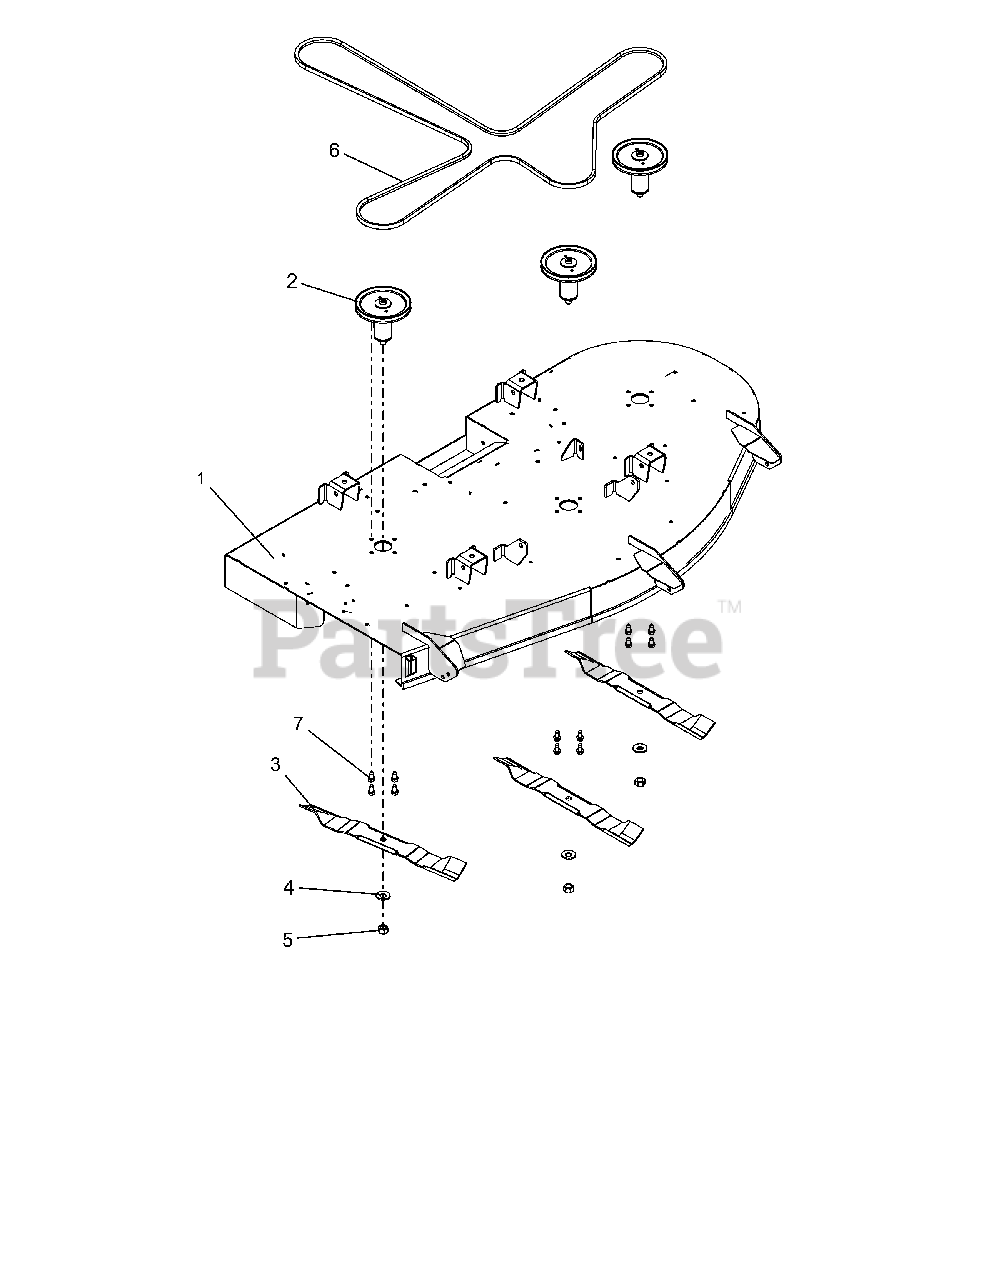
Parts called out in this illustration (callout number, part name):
1	KIT, 60" GRAVELY DECK W/DECALS
2	KIT, DECK SPINDLE ASM-60
3	BLADE, 21" 35 DEG
4	WSHR-BLVL .669X1.535X.138
5	NUT-STD .625-18 ZCC
6	BELT, HA
7	SCR,TAP .375-16X.75 HWH TR ZCC
